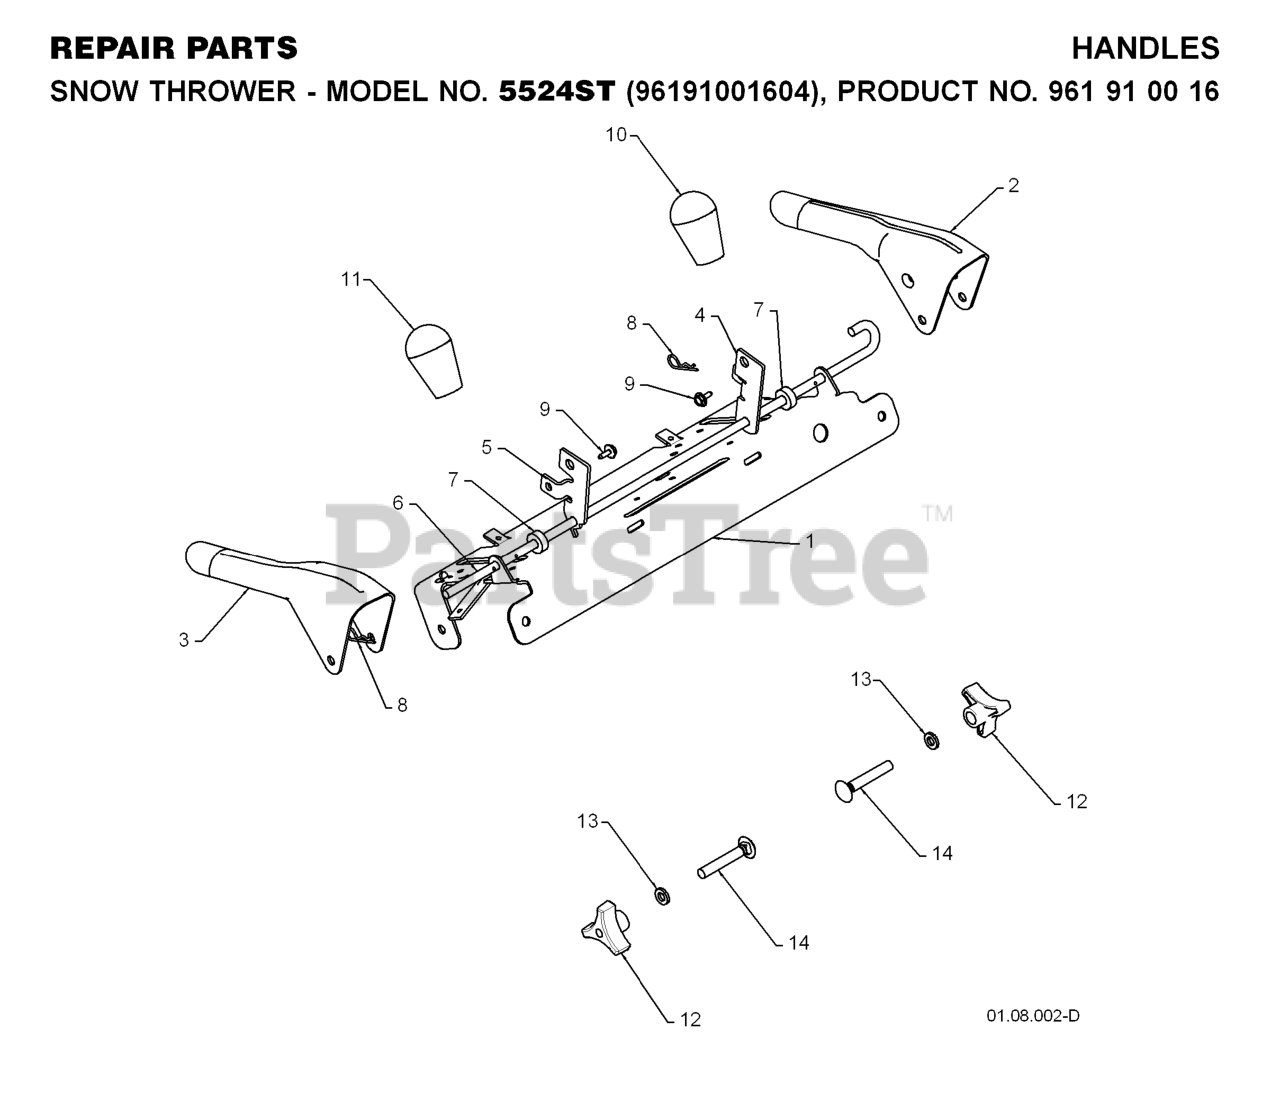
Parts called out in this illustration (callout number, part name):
1	PANEL.CONTROL.PNT.BLACK
2	LEVER.CONTROL.LH.PNT
3	LEVER.CONTROL.RH.PNT
4	ARM.TRACTION.ROD.YZ
5	ARM.IMPELLER.ROD.
6	BAIL.CONTROL.INTERLOCK
7	SPACER CONTROL LEVER
8	SPRING RETAINER
10	KNOB LEVER, BLACK
11	RED KNOB SHIFTER
12	KNOB.HANDLE.3/8.TRI-POINT.BLAC
13	WASHER
14	BOLT 3/8-16 X 2-1/4
